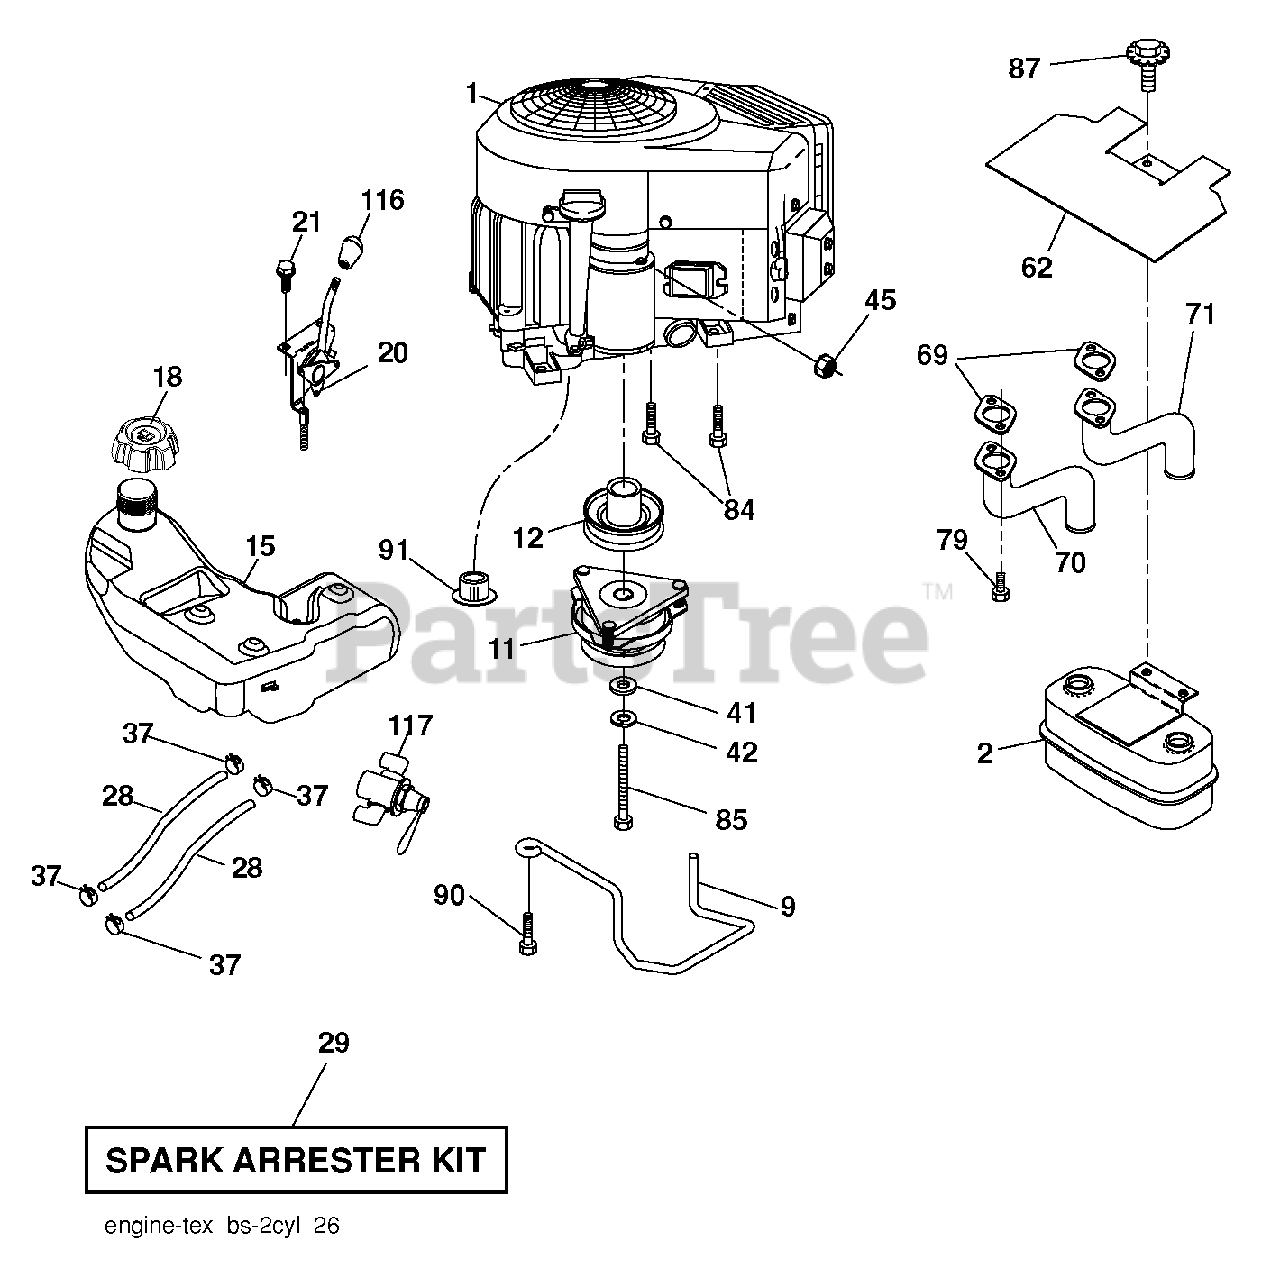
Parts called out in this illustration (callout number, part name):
2	MUFFLER.ASM.TWN.EXTNDED.DFLCTR
9	KEEPER.BELT.ENGINE.4.2
11	CLUTCH.ELECTRIC.LT.48"*
12	PULLEY.ENGINE.TUFFTORQ
18	CAP.FL.R.3'N/CARB.H.CROWN.498
20	CONTROL THROTTLE/CHOKE
21	SCREW.#10 X 0.750.BOS
28	LINE.FUEL.64"REAR.EMIS
29	KIT.SPARK ARRESTOR 794945 B&S
37	HOSE CLAMP
42	LOCKWASHER
45	NUT
62	SHIELD.HEAT.MUFFLER
69	GASKET.MUFFLER
70	RP.EXHAUST.TUBE.LH.BS/TWIN
71	EXHAUST.TUBE.RH.BS/TWIN
79	SCREW.SOCKET.HEAD.5/16-18
84	SCREW.3/8-16
85	BOLT HEX 7/16-20X4-1/4"
87	BOLT, 5/16-18 X 1 3/4
90	SCREW 3/8-16X1
91	BUSHING.1.375OD
116	KNOB - SHIFT
117	VALVE FUEL RESERVE
